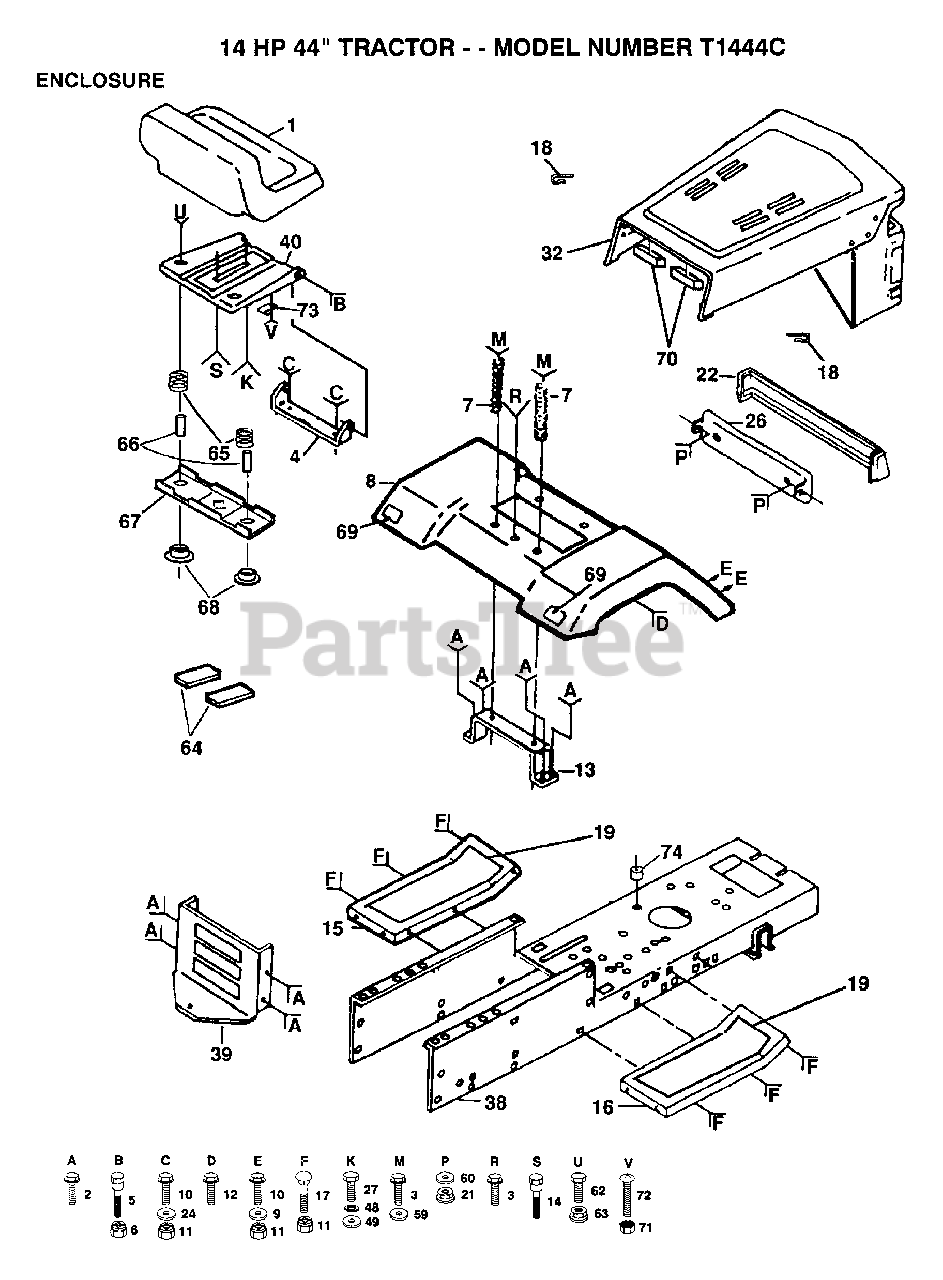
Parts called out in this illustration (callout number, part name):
2	SCREW
3	SCREW GTV
7	SPRING COMPRESSIO
9	WASHER
12	SCREW LT
14	"BOLT,SHOULDER"
17	BOLT
18	SPRING.RETAINER
19	FOOTREST PAD
21	PAL NUT LT
24	WASHER
27	BOLT
32	HOOD/GRILL ASM
38	CHASSIS ASM.
39	DRAWBAR LT/YT
48	LOCKWASHER
49	WASHER
59	WASHER
60	WASHER PM
64	STRIP FORM
65	SPRING COMPRESSED
66	SPACER SPLIT
67	BRKT SWITCH
68	BUSHING
69	REFLECTOR-TAIL YT
71	"NUT,KEPS"
74	SNAP BUSHING T
